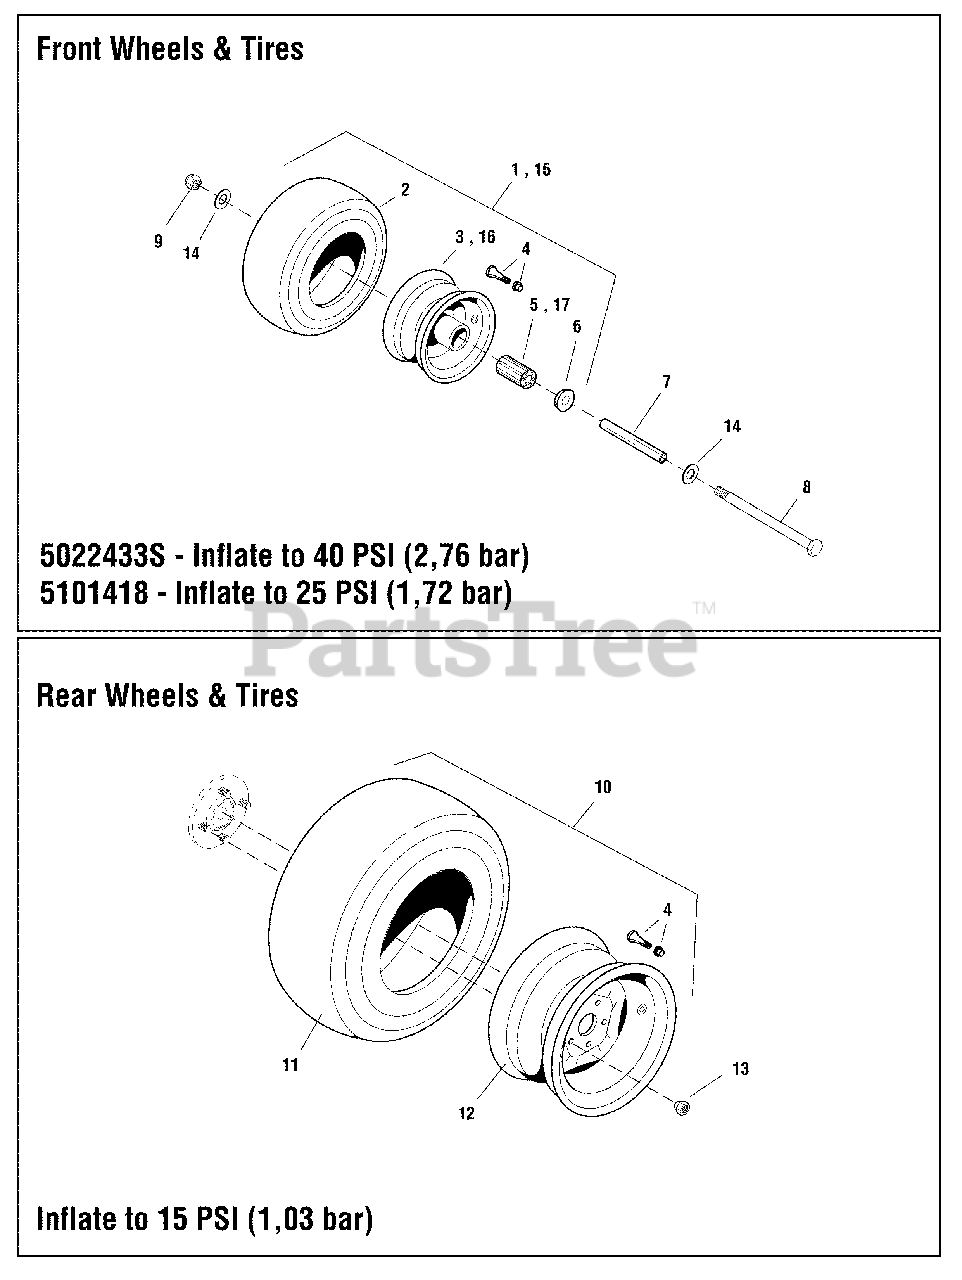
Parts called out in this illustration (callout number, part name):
2	TIRE, Caster, 11 X 4.0 - 5 (SV)
3	RIM, Caster, 11 X 4.0 - 5
4	VALVE STEM & CAP ASSEMBLY (SV)
5	BEARING, Roller
6	RETAINER, Bearing
7	AXLE, Caster
8	BOLT, Hex, 1/2-13 X 6-1/2, GD 8
9	NUT, Hex Nylon Lock, 1/2-13
10	TIRE ASSM, 20X8.00-10NHS, TURF MASTER
11	TIRE, Rear 20 X 8.0 X 10, TURF MASTER (SV)
12	WHEEL, 10X7.00 4/4 SOLID F237 2.625 OS (SV)
13	LUG NUT, 1/2-20
14	WASHER, SAE, 1/2
15	WHEEL, CASTER, 11 X 4.0-5 SILVER BEAD LO
16	WHEEL ASSEMBLY, 11 X 4.0 - 5 TIRE CMP (SV)
17	BEARING, CASTER WHEEL, 11 X 4.0 - 5 BEAD LOCK (SV)
